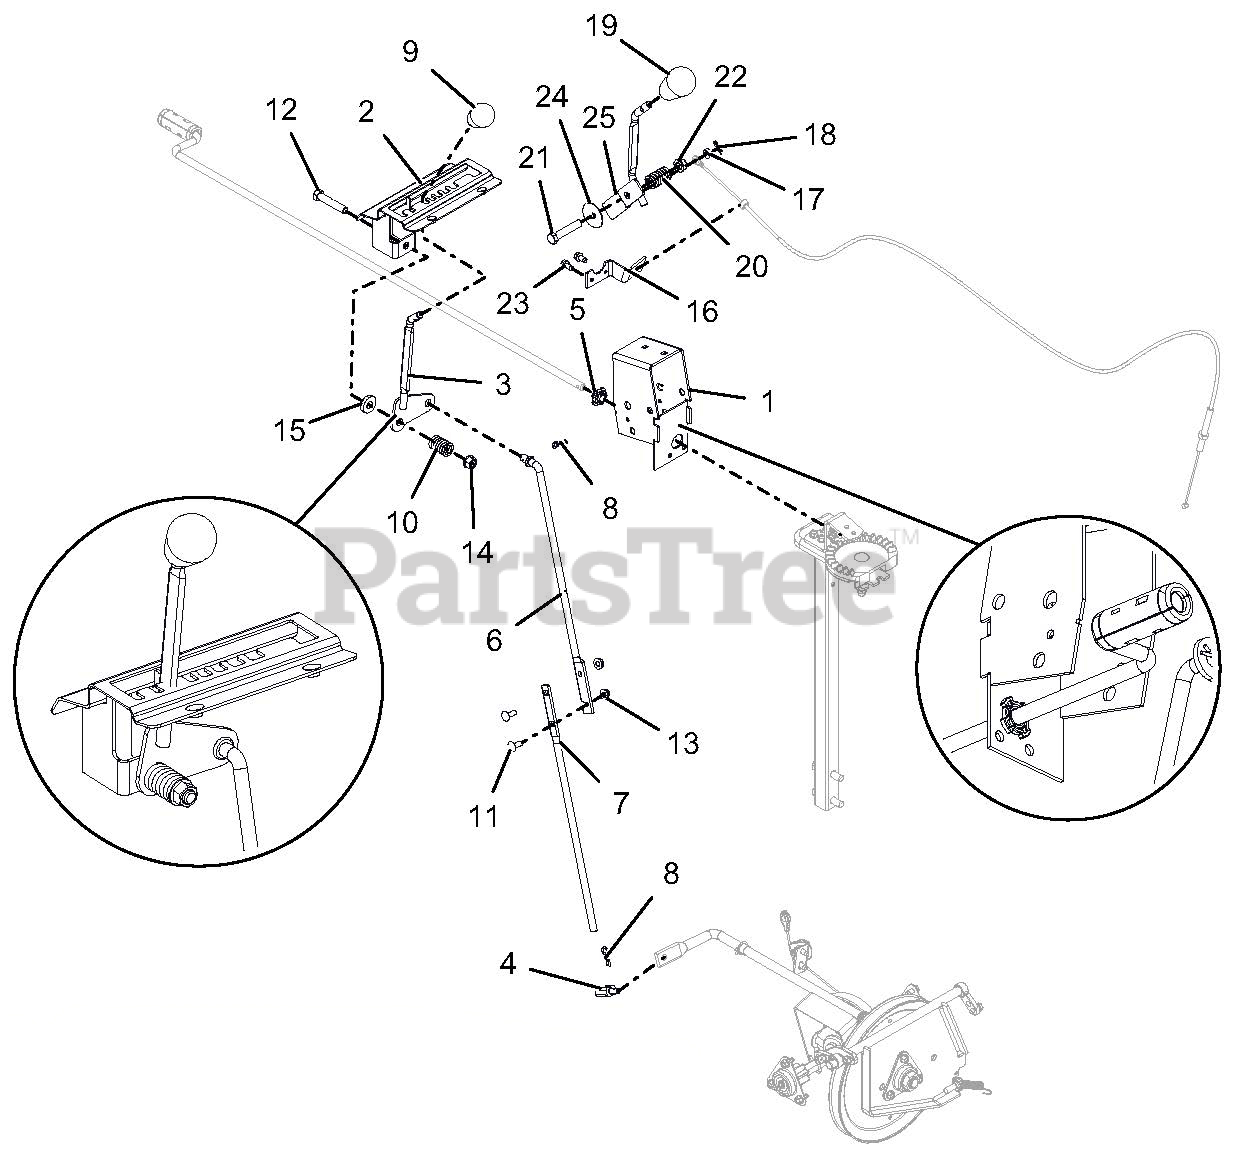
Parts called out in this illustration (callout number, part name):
1	WELDMENT, BRACKET INTERLOCK
2	WELDMENT, DETENT PLATE-COMPACT
3	LEVER, CONTROL-SHIFT(WELDMENT)
4	PIVOT,SHIFT ROD .375-16(TRUNN)
5	CRANK BUSHING, NYLON CHUTE BK
6	ROD, SHIFT - UPPER
7	ROD, SHIFT - LOWER
8	PIN-HAIR INT .08X.18X1.18 YWZC
9	KNOB,SOFT TEARDROP,PUSH-ON BLK
10	SG-COMP .125X.781X1.250
11	@BLT-RDHDSQNK .25-20X.75 G5YZ
12	@BLT-HEX .38-16X2.00 GR5 YWZC
13	@NUT-LK-CTR-FLG .25-20 YWZC
14	@NUT-LK-TOP-FLG .38-16 YWZC
15	WSHR-FL-STL .406X1.00X.188 YWZ
16	ANCHOR, DEFLECTOR CABLE
17	BSHG-SLV .265X.500X.219
18	PIN-HAIR INT .06X.18X.77
19	KNOB,SOFT TEARDROP,PUSH-ON GRY
20	SG-COMP .125X.781X1.250
21	@BLT-HEX .38-16X2.00 GR5 YWZC
22	@NUT-LK-TOP-FLG .38-16 YWZC
23	SCR-TAP .25-20X.50 HWH TR YWZ
24	WSHR-FL-STL .380X1.50X.062 YWZ
25	WELDMENT, CONTROL LEVER (DEFL)
